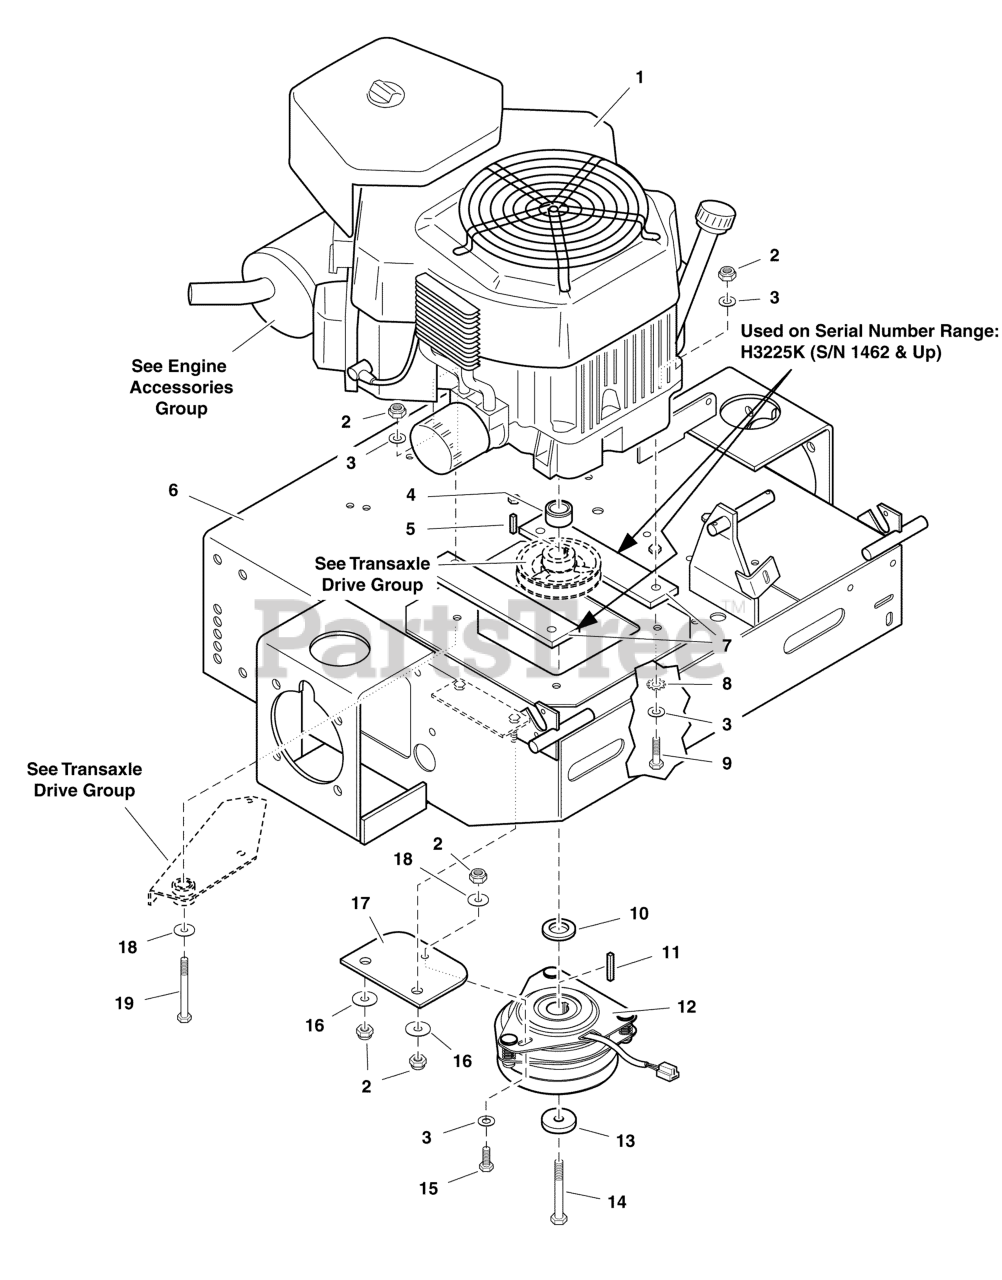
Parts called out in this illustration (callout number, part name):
2	NUT, 5/16-18 Hex Nylon Lock
3	WASHER, 5/16" SAE
4	SPACER, 1.13 X 1.75 X .88
4	SPACER, 1.13 X 1.75 X .50
5	KEY, 1/4" SQ. X 1-1/4
6	ENGINE DECK
7	SPACER, Engine Block
8	WASHER, 5/16" Internal Tooth Lock
9	BOLT, 5/16-18 x 1-3/4
9	BOLT, 5/16-18 x 1-1/4
10	SPACER, 1.13 x 1.75 x .62
10	SPACER, 1.13 x 2.00 x .19
11	KEY, 1/4 SQ. X 1
12	CLUTCH, Electric, 1-1/8" Shaft
13	SPACER, .45 x 1.62 x .37
14	CRANKSHAFT BOLT, 7/16 x 2-1/2
14	CRANKSHAFT BOLT, 7/16 x 3
15	BOLT, 5/16-18 X 3/4 GD5
16	WASHER, Clutch Anchor
17	CLUTCH ANCHOR PAD
18	WASHER, 5/16" Fender
19	BOLT, 5/16-18 x 3-1/2
19	BOLT, 5/16-18 x 3
